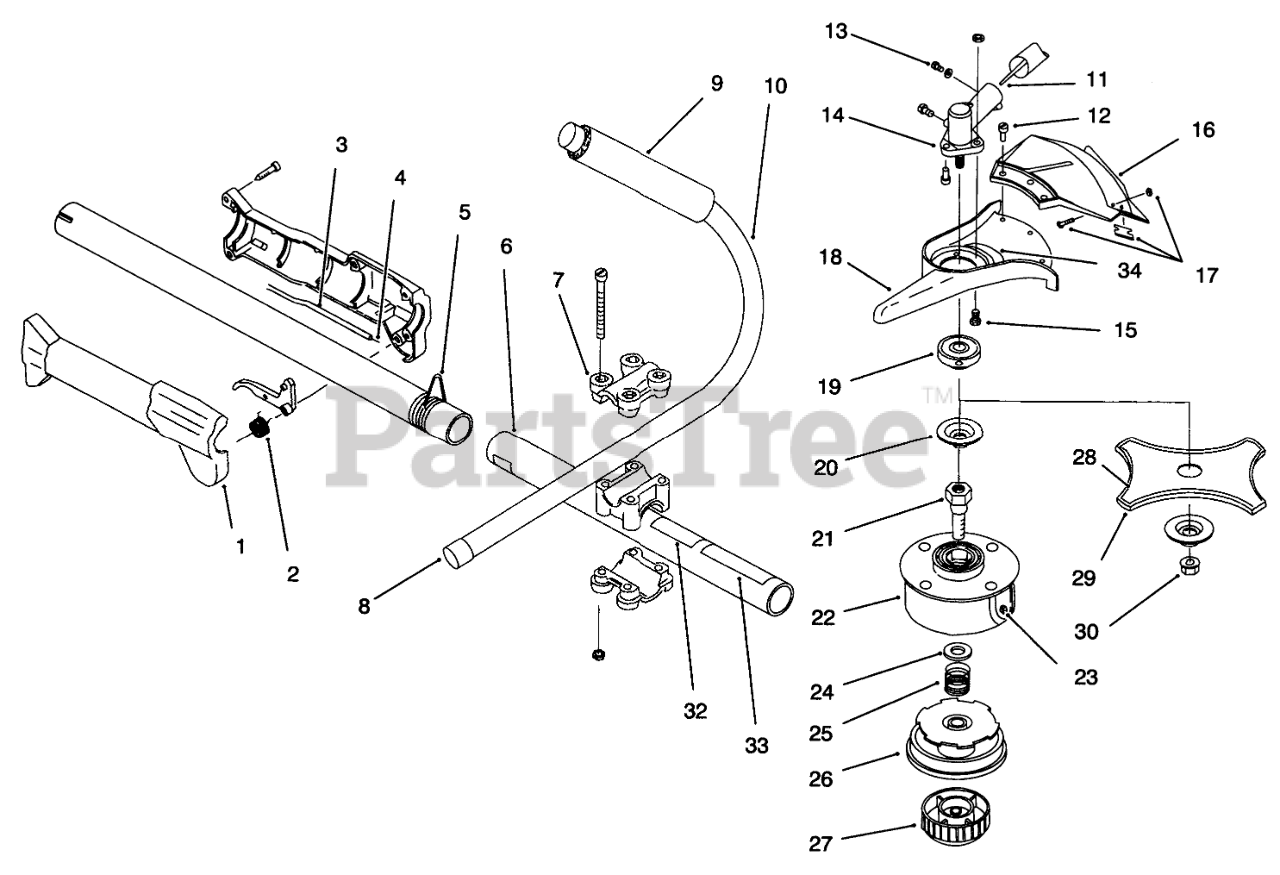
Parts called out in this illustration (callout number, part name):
1	ASM-THROTTLE HSG/TRIGGER
2	THROTTLE TRIGGER SPRING
3	Throttle Cable Housing
4	WIRE-THROTTLE
5	Clip-Shoulder Strap
6	DRIVE SHAFT HSG ASM
7	HANDLE BRACKET ASM
8	TUBE CLOSURE
9	HANDLE NITRILE GRIP
10	J-Handle Asm. (Incl. Ref. #8-9)
11	SHAFT - FLEXIBLE DRIVE
12	SCREWS - GUARD MOUNTING
13	MTG HDW&PLUG SET
14	Gear Box Asm. (Incl. Ref. #13, 19, 20, 30)
15	GUARD MNTG SCREW ASM
16	Guard and Blade Asm. (Incl. Ref. #17)
17	BLADE ASM
18	GUARD MOUNT
19	BLADE DRIVER
20	Blade Retaining Washer
21	SPOOL SHAFT
22	Outer Spool & Eyelet Asm.
23	EYELET
24	RETAINER ( 10 PACK)
25	SPRING
26	INNER REEL
27	BUMP HEAD KNOB ASSEMBLY
28	Blade
29	BLADE SAFETY GUARD
30	BLADE RETAINER NUT
32	Decal-Safety Symbol
33	DECAL - SAFETY
34	DECAL - WARNING
